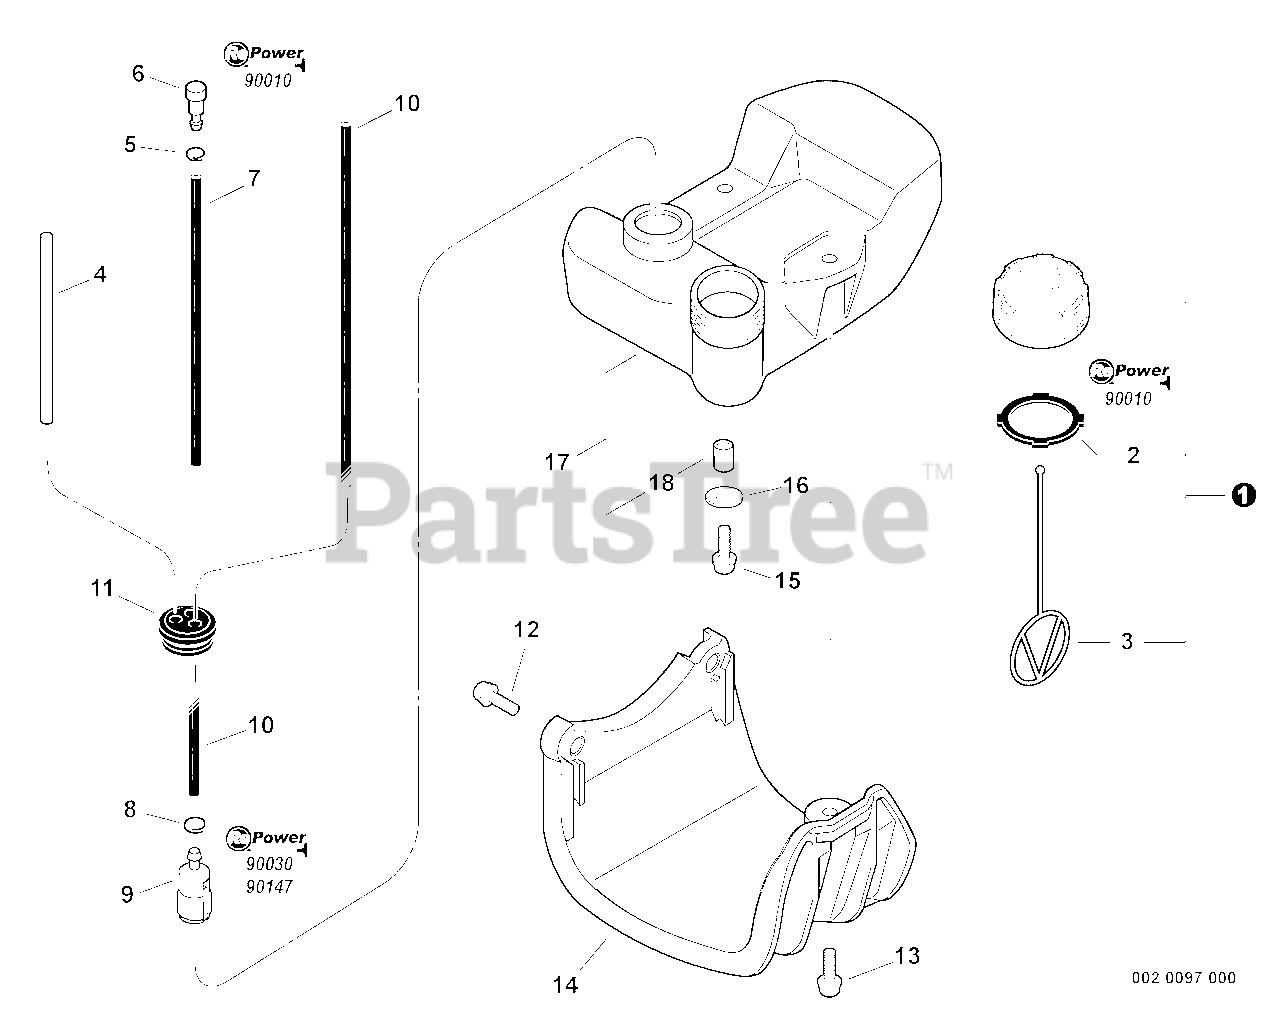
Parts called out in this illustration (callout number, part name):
1	CAP ASSY - ORANGE
2	GASKET, CAP
3	CONNECTOR, CAP
4	PIPE - 3X6X80 -- CLEAR
5	CLIP - 6.5
6	VENT, FUEL TANK
7	PIPE - 3X6X115 -- BLACK
8	CLIP - 6.5
9	FILTER, FUEL
10	PIPE - 3X6X170 -- BLACK
11	GROMMET
12	SCREW - 5X22
13	SCREW - 5X20
14	GUARD, FUEL TANK
15	SCREW - 5X16
16	WASHER - 5
17	FUEL TANK ASSY
19	Repower CAP AND VENT KIT
20	RePower FILTER KIT
21	RePower TUNE-UP KIT
